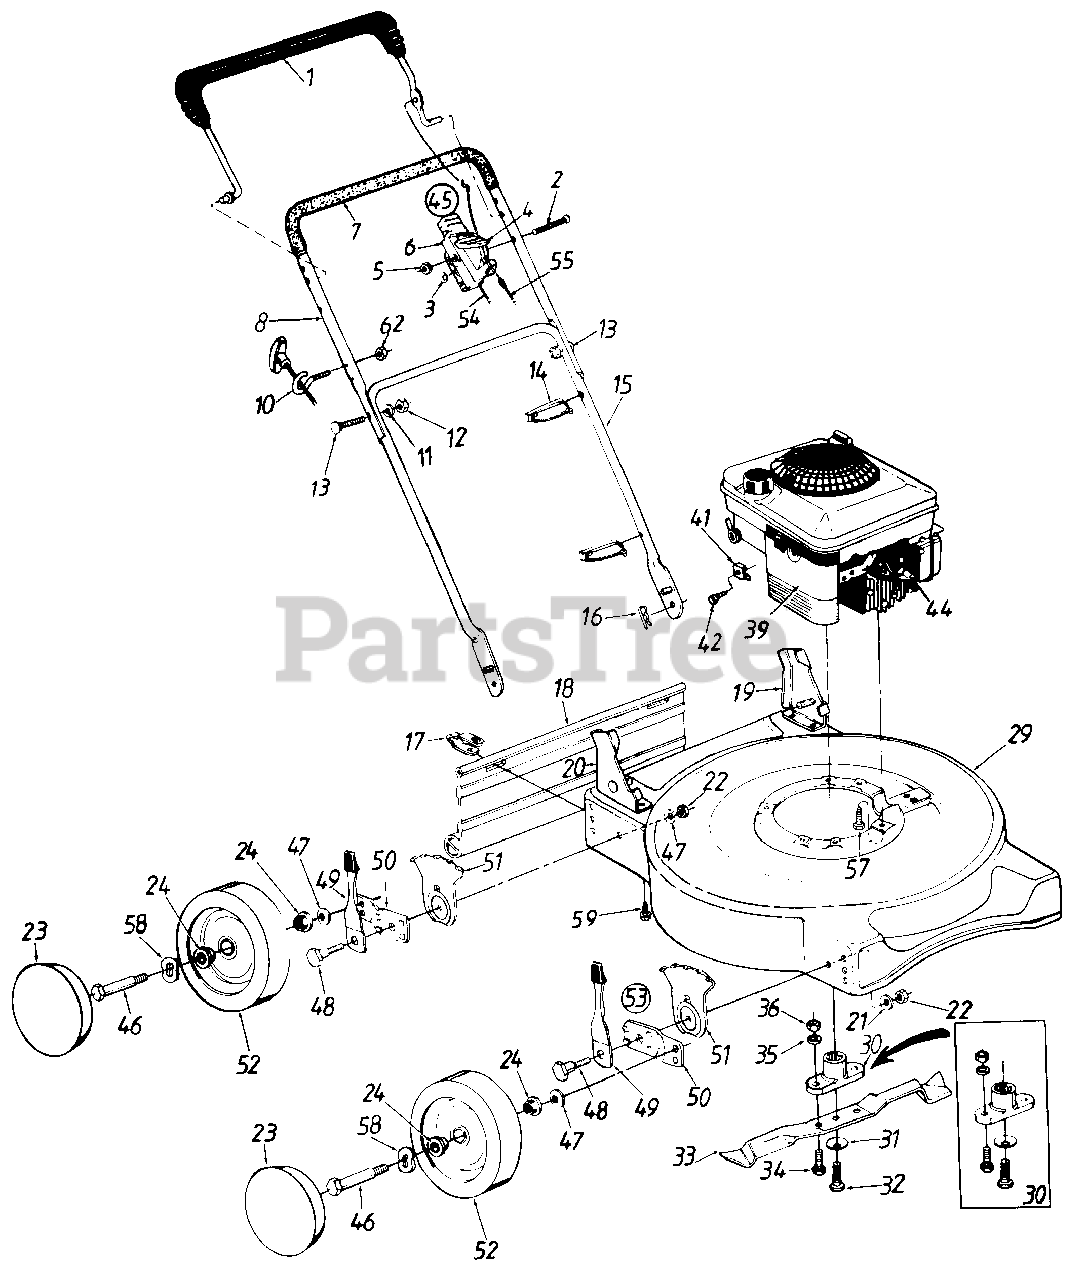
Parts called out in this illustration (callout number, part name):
1	Control Handle Ass'y.
2	Oval C-Sunk Scr.
3	Spr. Wash. .66" I.D.
4	Throttle Lever
5	Hex L-Nut 1/4-20 Thd.
6	Throttle Body
7	Grip
11	L-Wash. 5/16" I.D.
12	Hex Nut 5/16-18 Thd.
13	Curved Carriage Bolt 5/16-18 x 1.38" Lg.
14	Cable Tie
15	Lower Handle
16	Hairpin Cotter
17	Hinge Clip
18	Rear Flap
19	Handle Bracket Ass'y.--L.H.
20	Handle Bracket Ass'y.--R.H.
21	Bell-Wash. .39" I.D. x 1.38"
22	Hex Nut 3/8-16 Thd.
23	Hub Cap
24	Bearing
29	20" Deck Ass'y.
30	Blade Adapter Kit
31	Bell-Wash. .46" I.D.
32	Hex Bolt 7/16-20 x 1.5" Lg.
33	20" Mulching Blade
34	Hex Bolt 3/8-24 x 1" Lg.
35	L-Wash. 3/8" I.D.
36	Hex Nut 3/8-24 Thd.
39	Engine
41	Cable Clamp
42	Hex Self-Tap Scr. #10-32 x .62"
44	Spark Plug Boot
45	Throttle Box Comp.
46	Axle Bolt
47	Bell-Wash. .400" I.D. x .88"
48	Shld. Bolt .50" Dia. x .357"
49	Spring Lever Ass'y. w/Knob
51	Height Adj. Plate
52	Wheel Ass'y. Comp.
53	Height Adj. Ass'y. Comp.--R.F. & L.R.
54	Throttle Cable--51"
55	Control Cable--39"
57	Hex L-Wash. Hd. Scr. 3/8-16 x 1.0" Lg.
58	Wave Washer .53" I.D.
59	Hex Wash. Hd. B-Tap Scr. 5/16-18 x .5" Lg.
62	Hex L-Nut 1/4-20 Thd.
